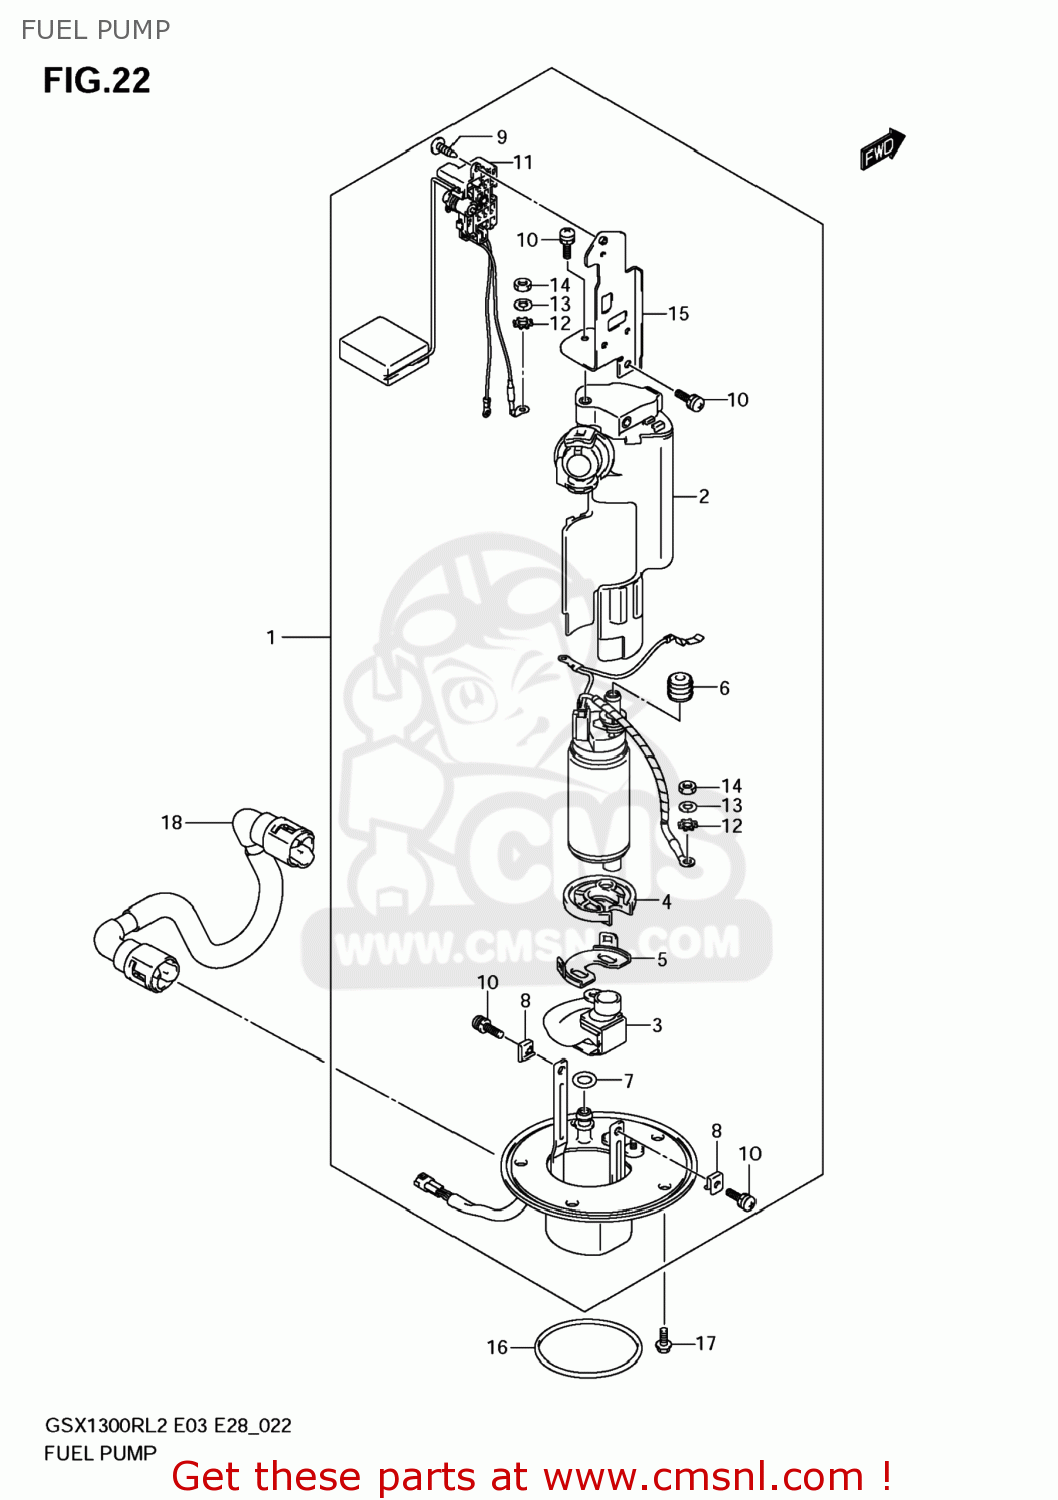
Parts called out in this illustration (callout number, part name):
1	PUMP ASSY,FUEL
2	FILTER,FUEL
3	STRAINER,FUEL
4	CUSHION
5	HOLDER,FUEL PUMP
6	BUSH,FUEL PUMP
7	O RING
8	NUT
9	SCREW
10	SCREW
11	GAUGE ASSY,FUEL LEVEL
12	WASHER
13	WASHER,SPRING
14	NUT
15	BRACKET,FUEL GAUGE
16	O RING,FUEL PUMP
17	BOLT
18	HOSE,FUEL
